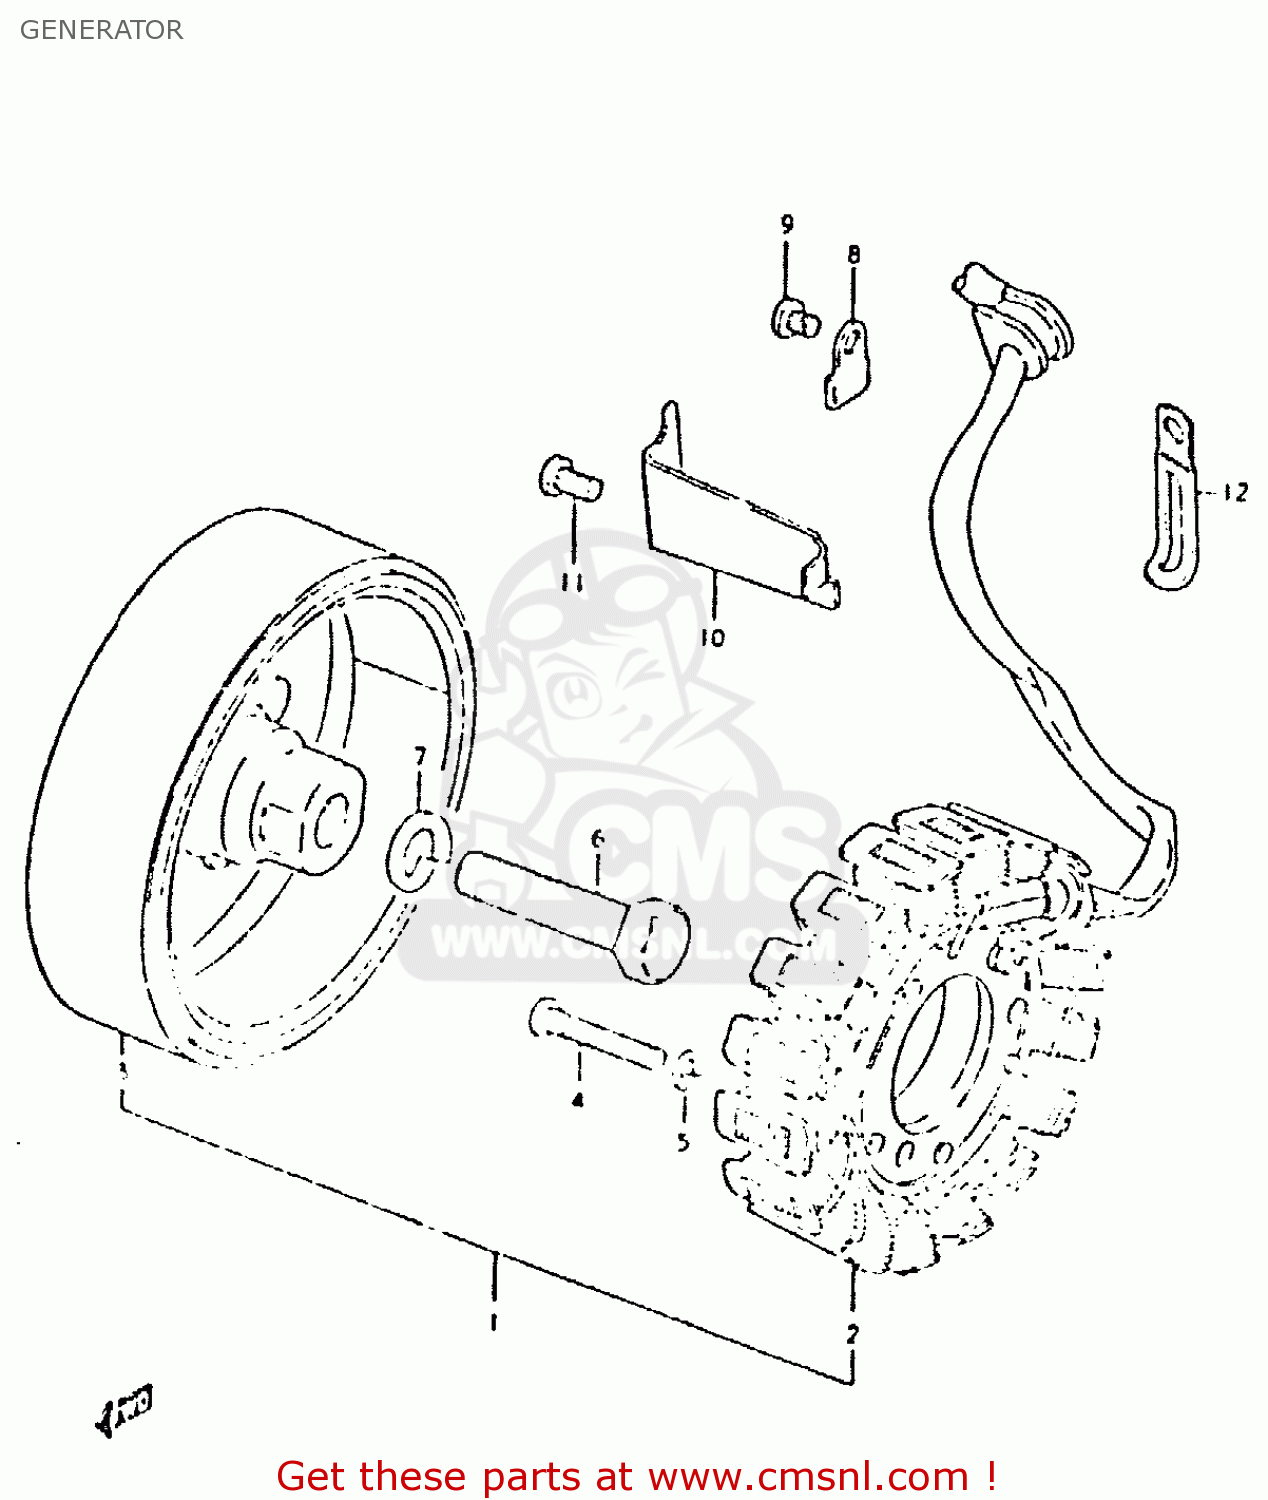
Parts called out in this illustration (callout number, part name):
1	GENERATOR ASSEMBLY
2	STATOR ASSEMBLY
3	ROTOR ASSEMBLY
4	SCREW
5	LOCK WASHER
6	BOLT 12X45
7	WASHER,LOCK 12
8	CLAMP,GENERATOR LEAD WIRE
9	SCREW
10	CLAMP,GENERATOR LEAD WIRE
11	SCREW
12	CLAMP L:35
